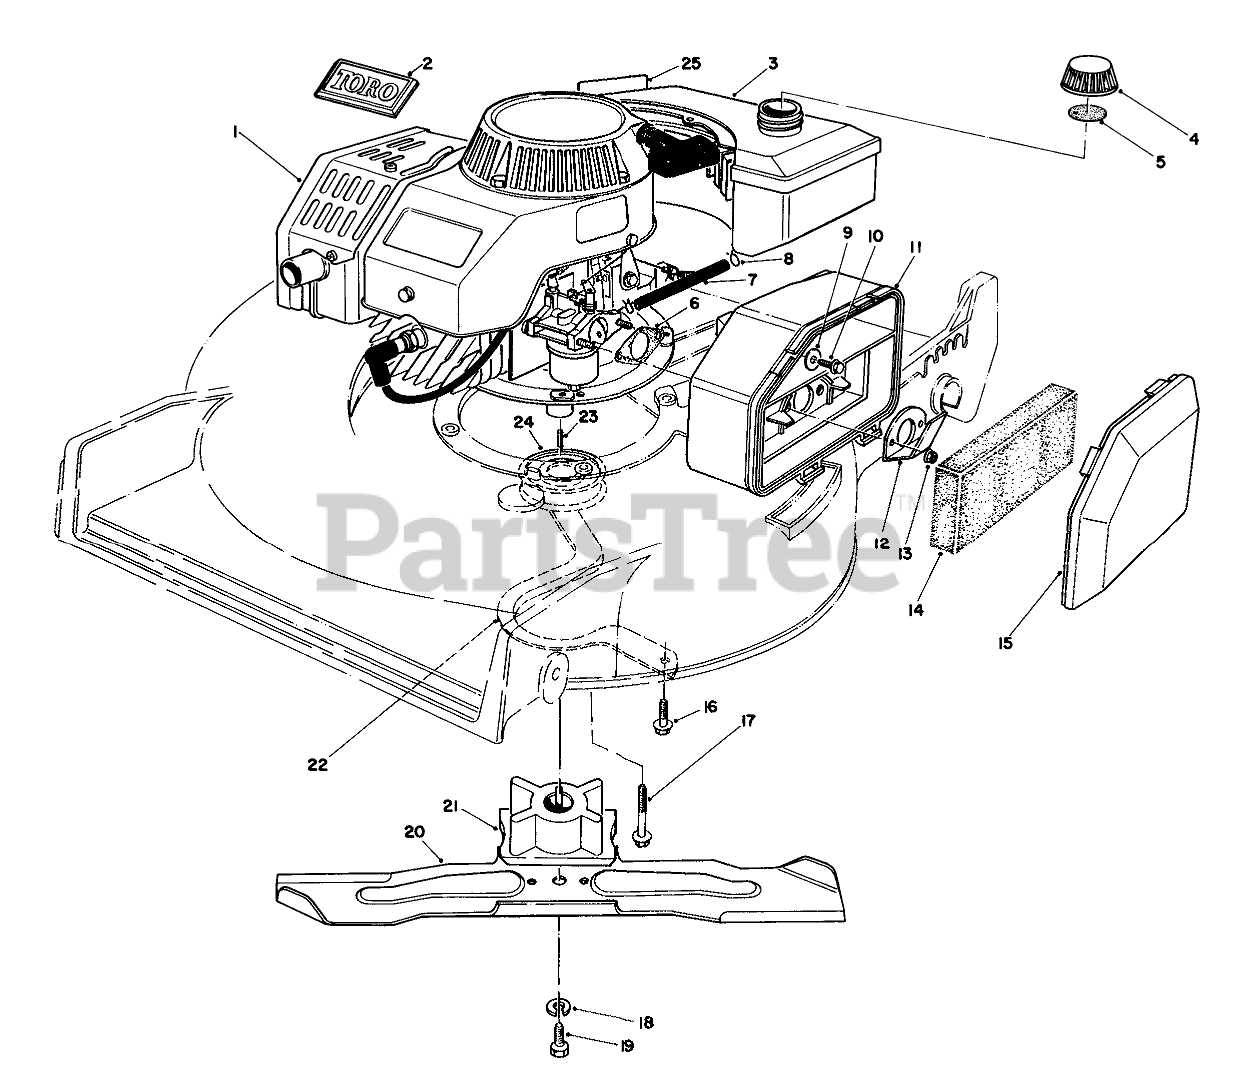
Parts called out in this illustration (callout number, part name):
1	Engine
2	TORO LOGO PLT
3	Gas Tank Assembly
4	Gas Cap Assembly (Incl. Ref. #5)
5	GAS CAP GASKET
6	GASKET-AIR CLEANER
7	FUEL LINE
8	FUEL LINE CLAMP
9	WASHER-FLAT
10	SCREW-HH
11	AIR CLEANER
12	SPIT BACK DEFLECTOR
13	NUT-LOCK
15	AIR CLEANER COVER
16	Screw
17	SCREW-HHF
18	WASHER-LOCK
19	SCREW-BLADE
20	BLADE-21in
21	Retainer Blade
22	BELT GUIDE
23	PULLEY-DRIVER
24	KEY-SQUARE
25	Decal-Maintenance
